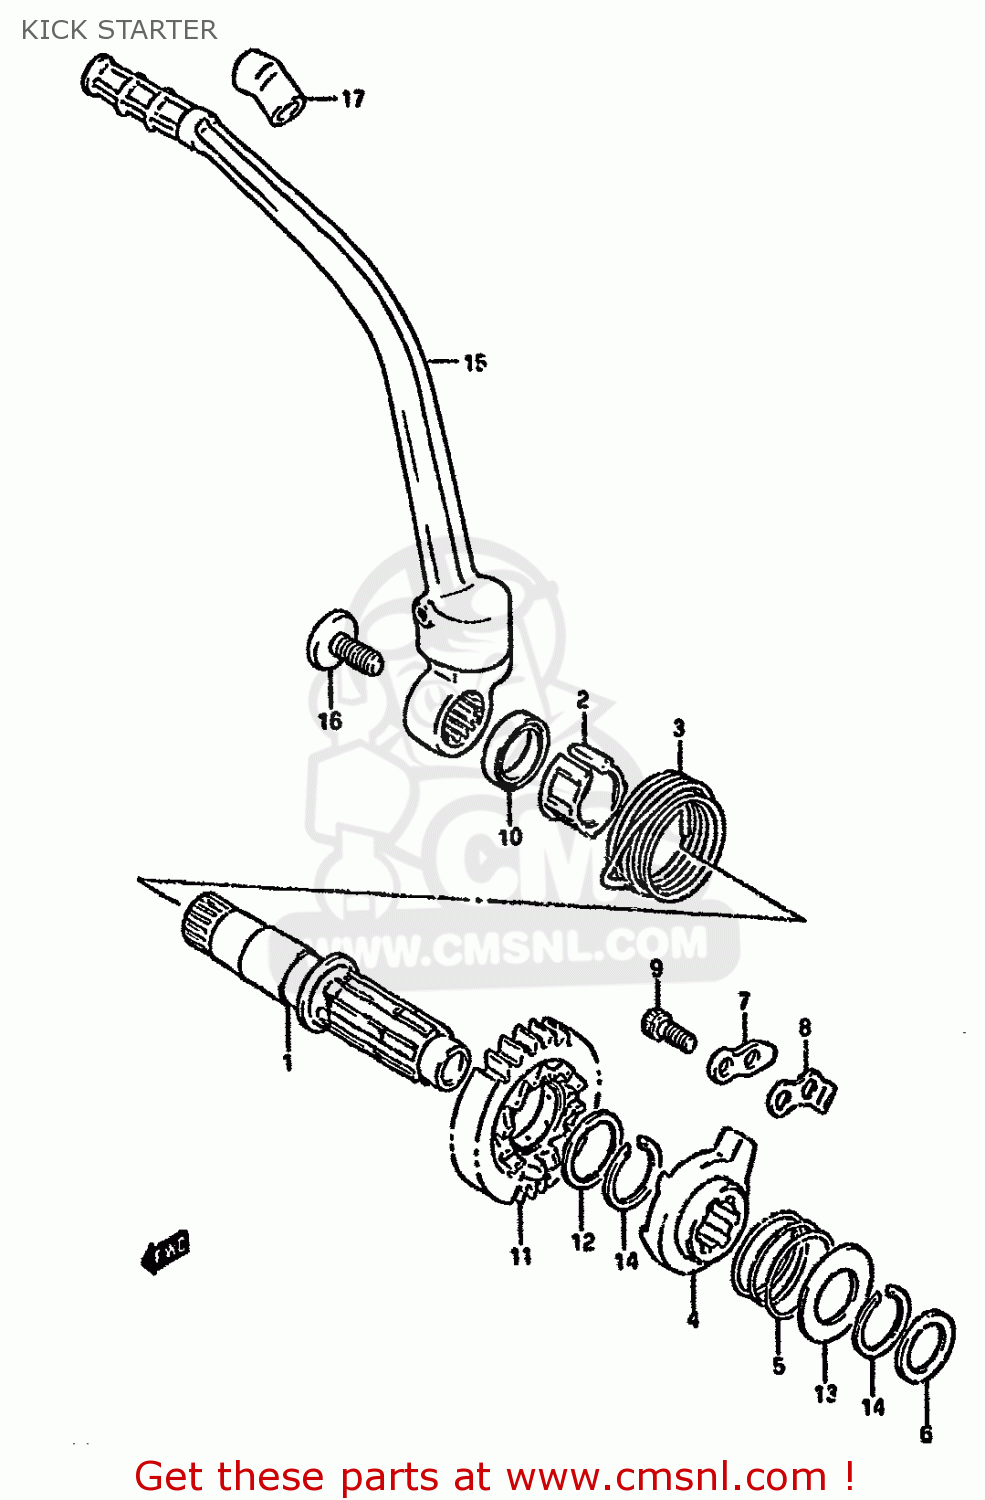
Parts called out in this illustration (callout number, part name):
1	SHAFT,KICK STARTER
2	GUIDE,KICK STARTER SFT SPRING
3	SPRING
4	STARTER,KICK
5	SPRING
6	WASHER,THRUST
7	GUIDE,KICK STARTER
8	STOPPER,KICK STARTER
9	BOLT,KICK START STOPPER
10	SEAL,OIL(20X27X6)
11	GEAR,KICK STARTER NO.2
12	SHIM
13	WASHER,THRUST
14	CIRCLIP
15	LEVER ASSEMBLY,KICK STARTER
16	BOLT(8X14)
17	COVER,KICK STARTER LEVER
